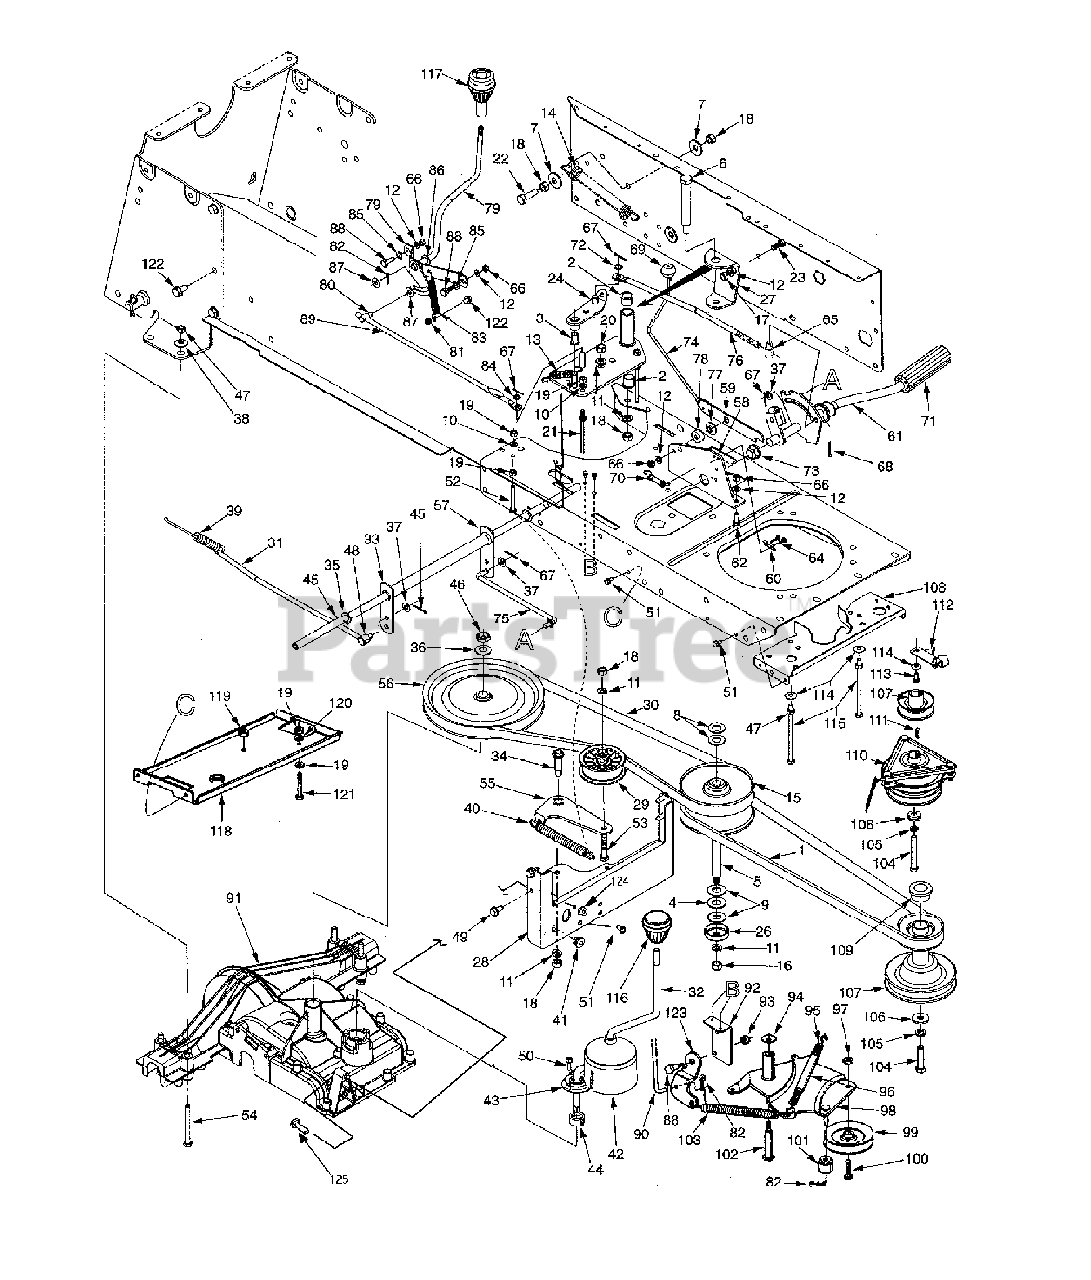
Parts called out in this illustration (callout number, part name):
1	"V"-Belt
2	Flange Brg.
3	Flange Nyliner Brg.
4	Thrust Brg.
5	Shaft
6	Shld. Bolt 3/8-24 Thd.
7	Bell-Wash. .396" I.D. x 1.14" O.D.
8	Fl-Wash. .56" I.D. x 1.12" O.D.
9	Fl-Wash. .5" I.D. x 1" O.D.
10	L-Wash. 1/4" I.D.
11	L-Wash. 3/8" I.D.
12	L-Wash. 5/16" I.D.
13	Ext. Spring 2.54" Lg.
14	Ext. Spring 6.96" Lg.
15	Variable Speed Pulley
16	Hex L-Nut 3/8-24 Thd.
17	Hex Nut 5/16-24 Thd. (Gr. 5)
18	Hex Nut 3/8-16 Thd. (Gr. 5)
19	Hex Nut 1/4-20 Thd. (Gr. 5)
20	Hex Nut 3/8-24 Thd.
21	Belt Keeper
22	Hex Bolt 3/8-16 x 1.25" Lg.
23	Hex Bolt 5/16-24 x .75" Lg. (Gr. 5)
27	Support Brkt.
30	"V"-Belt
31	Brake Rod
32	Shift Lever
33	Flange Nyliner Brg.
34	Shld. Bolt 3/8-16 Thd.
35	Fl-Wash. .5" I.D. x .875" O.D.
36	Bell-Wash. .567" I.D. x 1.125" O.D.
37	Fl-Wash. 5/16" I.D.
38	Bell-Wash. .345" I.D. x .88" O.D.
39	Ext. Spring 7.3" Lg.
40	Ext. Spring 6.12" Lg.
41	Plastic Bushing
42	Boot Shifter
43	Shifter Snout
44	Shifter Insert
45	Cotter Pin 1" Lg.
46	Hex Jam Nut 9/16-18 Thd.
47	Hex Nut 5/16-18 Thd. (Gr. 5)
48	Ferrule
49	Hex Wash. AB-Tap Scr. 5/16-18 Thd.
50	Hex Wash. TT-Tap. Scr. 1/4-20 x .75" Lg.
51	Hex Wash. Hd. TT-Tap Scr. 1/4-20 x .5" Lg
52	Hex Bolt 1/4-20 x 2" Lg. (Gr. 5)
53	Hex Bolt 3/8-16 x 1.75" Lg. (Gr. 5)
54	Hex Bolt 5/16-18 x 3" Lg. (Gr. 5)
56	Trans. Pulley
64	Hex Hd. Tap Scr. #10-16 x .75" Lg.
65	Ferrule
66	Hex Nut 5/16-18 Thd.
67	Cotter Pin 1" Lg.
68	Cotter Pin 1/8" Dia. x 1" Lg.
69	Ball Knob
70	Ext. Spring 2.51" Lg.
71	Foot Pad
72	Fl-Wash. 3/8" I.D. x .62" O.D.
73	Hex Flange Bearing
74	Pedal Lock Rod
75	Brake Link Rod
76	Speed Control Link
77	Shld. Spacer
78	Spacer .34" I.D. x .87" O.D.
79	Speed Selector Lever Ass'y.
80	Ferrule
81	Hex L-Nut 5/16-18 Thd.
82	Hairpin Clip
83	Ext. Spring 3.97" Lg.
84	Fl-Wash. 3/8" I.D. x .62" O.D.
85	Spr. Wash. 7/16" I.D.
86	Fl-Wash. .531" I.D. x .93" O.D.
87	Fl-Wash. 3/8" I.D. x .87" O.D.
88	Shld. Bolt .437" x .286"
89	Speed Control Link Rod
90	Deck Control Rod
91	Transmission Complete
92	Parking Brake Mtg. Brkt.
93	Hex L-Nut 5/16-18 Thd.
94	Bell-Wash. .38" I.D. x .88" O.D.
95	Extension Spring 6.37" Lg.
96	Conduit 4" Lg.
97	Hex Cent. L-Nut 3/8-24 Thd.
98	Idler Brkt. Deck Ass'y.
99	"V"-Belt Idler
100	Hex Bolt 3/8-24 x 1.5" Lg.
101	Spacer
102	Shld. Bolt .498" Dia. x 2.05"
103	Extension Spring 6.12" Lg.
104	Hex Bolt 7/16-20 x 2.75" Lg.
105	L-Wash. 7/16" I.D.
106	Fl-Wash. .44" I.D. x 1.25" Lg.
107	Engine Pulley
110	Electric PTO
111	Sq. Key 1/4" x 1" Lg.
114	Bell-Wash. .345" I.D. x .88" O.D.
115	Hex Bolt 5/16-18 x 5.25" Lg.
116	Knob
117	Shift Knob
119	Hex Cent. L-Nut 3/8-16 Thd.
120	L-Wash. 1/4" I.D.
121	Hex Bolt 1/4-20 x 2" Lg.
122	Hex AB-Tap Scr. 5/16 x .75" Lg.
123	Deck Control Pivot Brkt.
124	Hex L-Nut 5/16-18 Thd.
125	Hex Bolt 5/16-18 x 1.375" Lg.
